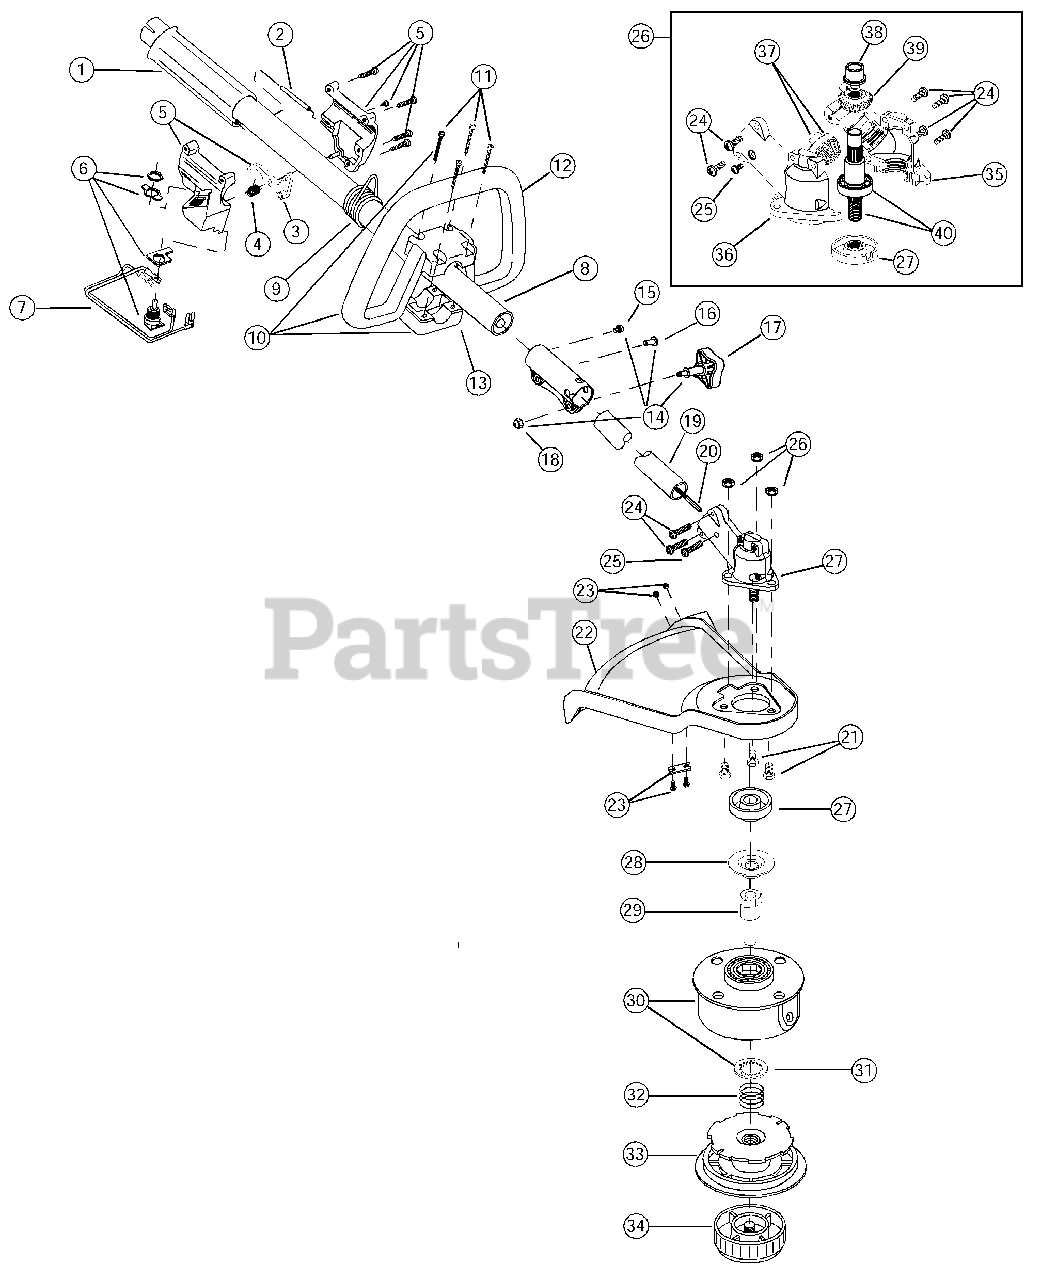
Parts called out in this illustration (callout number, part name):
2	Throttle Cable Assembly
3	Throttle Trigger
4	Throttle Trigger Spring
5	Throttle Trigger Assm
6	Switch Assembly
7	Wire Lead Assembly
8	Upper Drive Shaft Housing Assm
9	Shoulder Harness Clamp
10	Loop Handle Assembly
12	Loop Handle
13	Bottom Clamp
14	Click-Link Coupler
17	Adjustment Knob
18	Knob Retaining Nut
19	Lower Drive Shaft Housing
20	Drive Shaft
21	Shield Mount Screw Assm
22	Shield & Blade Assm
23	Blade Assembly
24	Gearbox Mounting Hardware
25	Anti-Rotation Screw
26	2 Pc Gearbox Assm
27	Blade Driver
28	Retaining Washer
29	Spool Shaft
30	Outer Spool & Eyelet Assembly
31	Retainer
32	Spring
33	Inner Reel
34	Bump Head Knob Assembly
35	Left Housing
36	Right Housing
37	Pinion Gear Assembly
38	Output Shaft Bushing
39	Output Shaft Gear
40	Output Shaft Assembly
